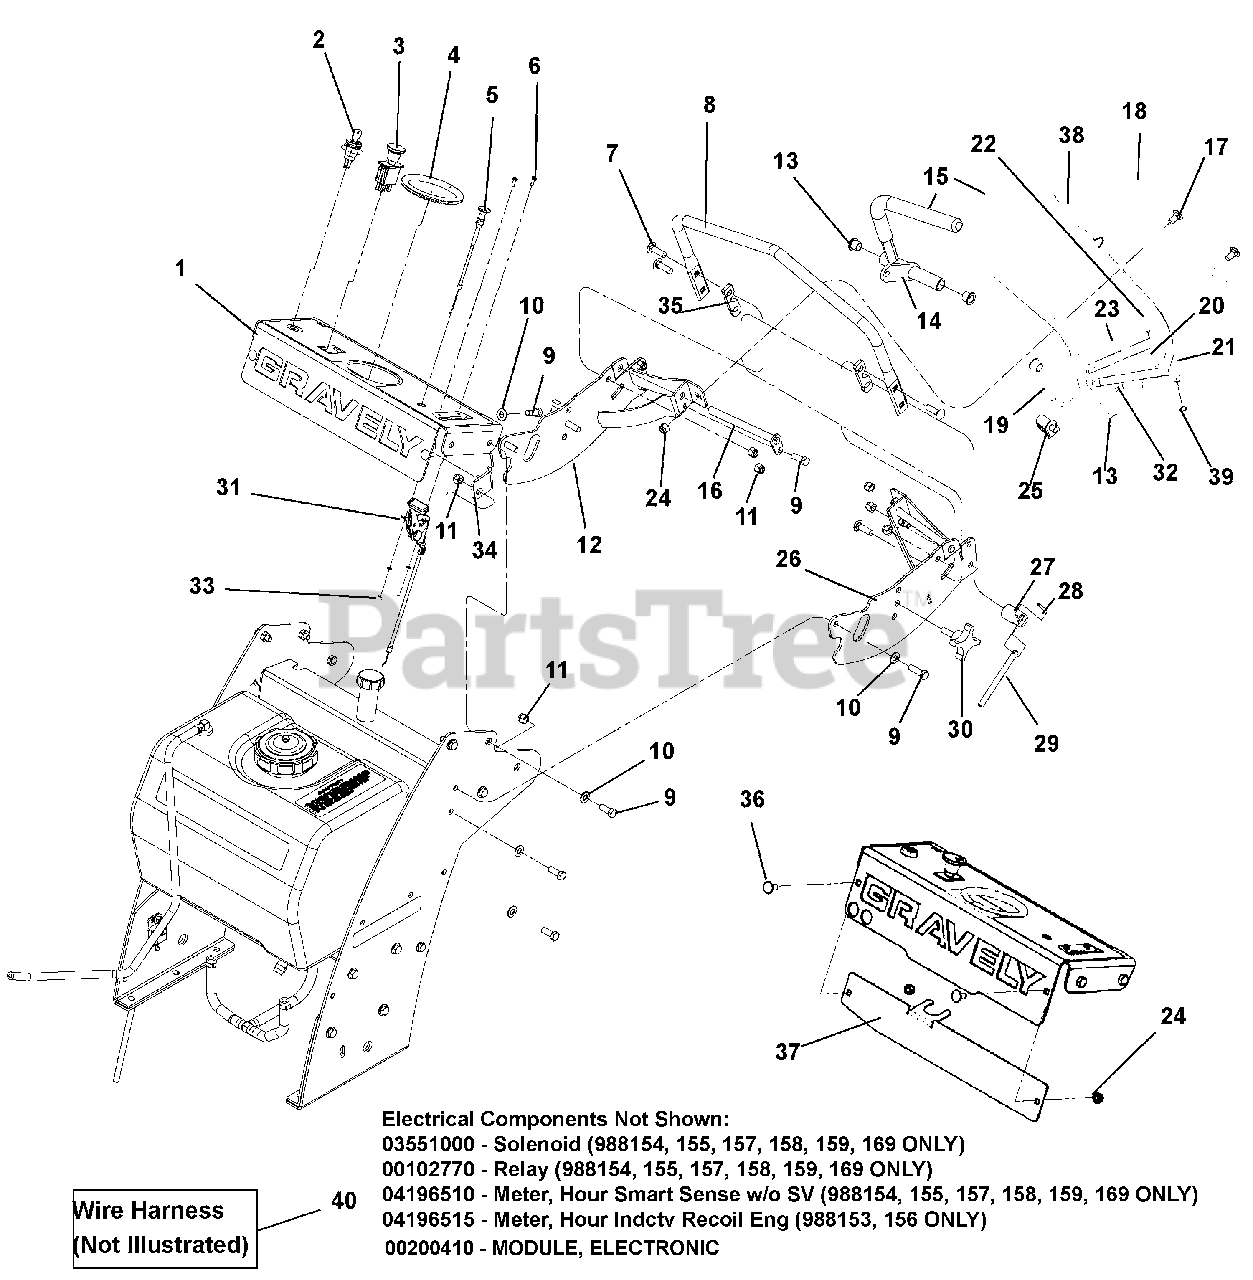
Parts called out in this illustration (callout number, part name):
1	ASSY, CONSOLE W/DECALS
1	ASSY, CONSOLE W/DECALS GRV PS
2	SWITCH, TWO POSITION KEY
2	SWITCH, THREE POSITION KEY
3	SWITCH, CLUTCH W/GRAPHIC
4	TRIM, RUBBER EDGE 12"
5	CABLE, CHOKE 48"
5	CABLE, CHOKE 43"
5	CABLE, CHOKE
6	SCR-PANHDSLT 8-32X.50 YWZC
6	SCREW-MACHINE 10-24X.75 HEX WASHER HEAD
7	BOLT, RDHDSQNK .38-16 X 1.25 G5
8	SUPPORT, HANDLE
8	SUPPORT, HANDLE RED
9	BOLT, HEX .38-16 X 1.00 GR5 Y
10	WASHER, .406 X .813 X .065 FLAT Y
11	LOCKNUT, .38-16 NYLOC Y
12	WLDT, RH CONTROL MOUNT
12	WMT,RH CONTROL MOUNT
13	BRG, FLG .500 X .625 X .500 BRNZ
14	WLDT, RH DRIVE LEVER
15	GRIP, CONTROL
16	WLDT, PIN AND LOCK
17	BLT-RDHDSQNK .38-16X1.00 G5YWZC
18	WMT, REVERSE BAR
19	WLDT, LH DRIVE LEVER
20	BUSHING, OPERATOR PRESENCE
21	WLDT, OPC HANDLE
22	BOLT, .25-20 X 2.00 HEX 5
23	BUMPER, RUBBER
24	NUT-LK-NYL .38-16 YWZC
25	SWITCH, SEAT OVER RIDE
26	WLDT, LH CONTROL MOUNT
26	WMT,LH CONTROL MOUNT
27	BASE, LOCK LEVER Y
28	PIN, SPRING
29	LEVER, LOCK
30	KNOB, 3/8 X 1.25 - 4 PRONG
30	KNOB, 3/8 -16 X .75
31	CABLE, THROTTLE - 49.5
31	CABLE, THROTTLE 43"
31	CABLE, THROTLE 49.5"
32	NUT-SPNLK-FLG .312-18 YWZC
33	NUT-LK-NYL 8-32 W/INSTR YWZC
33	NUT-LK-NYL 10-24 W/INSRT
34	PLATE, HANDLE BRACE
34	WLDT, HANDLE BRACE G2
35	SHIM, 5 DEG SPEED BAR
36	BOLT-RDHDSQNK .31-18X.75 G5
37	BRACKET, REMOTE ROV HYDRO
38	GRIP, CLUTCH LEVER
39	NUT, LK-CTR .25-20
